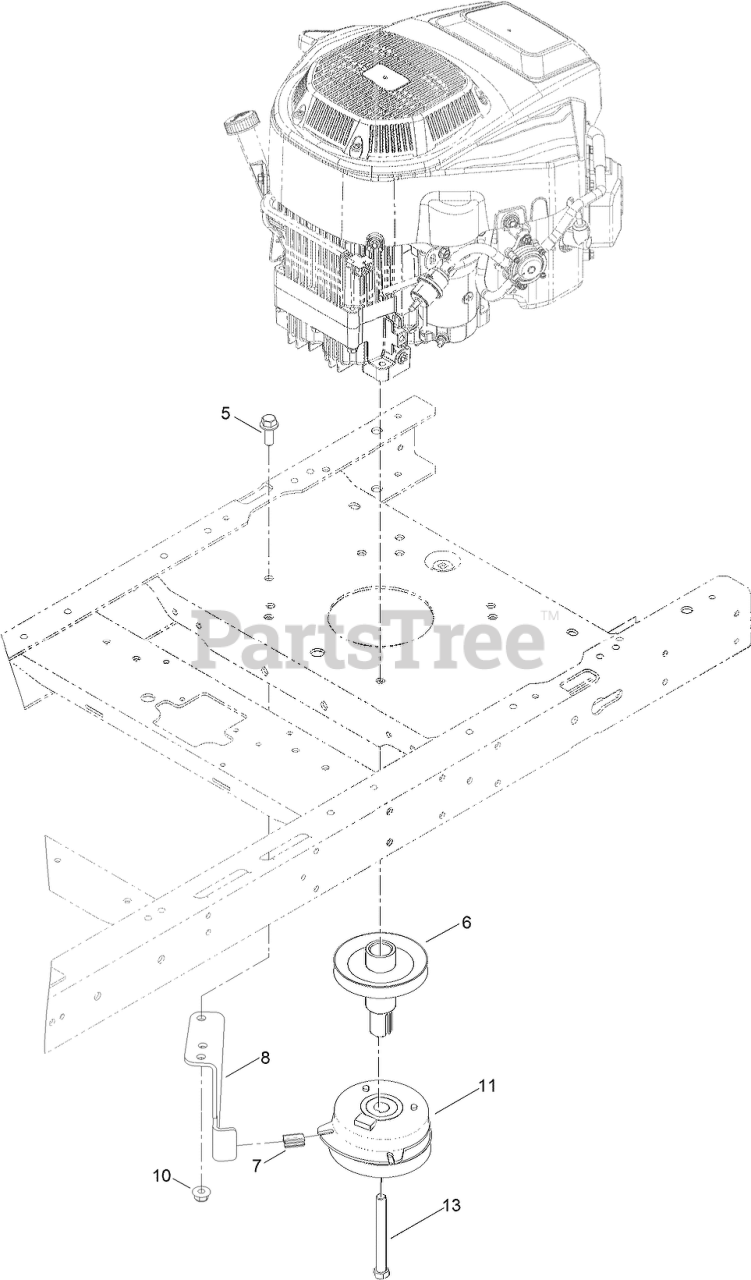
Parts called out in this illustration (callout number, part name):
5	SCREW-HHF
6	PULLEY-ENGINE
7	ISOLATOR-CLUTCH
8	STOP-CLUTCH
10	NUT-HF, NI
11	CLUTCH-PTO
13	Screw-HH
